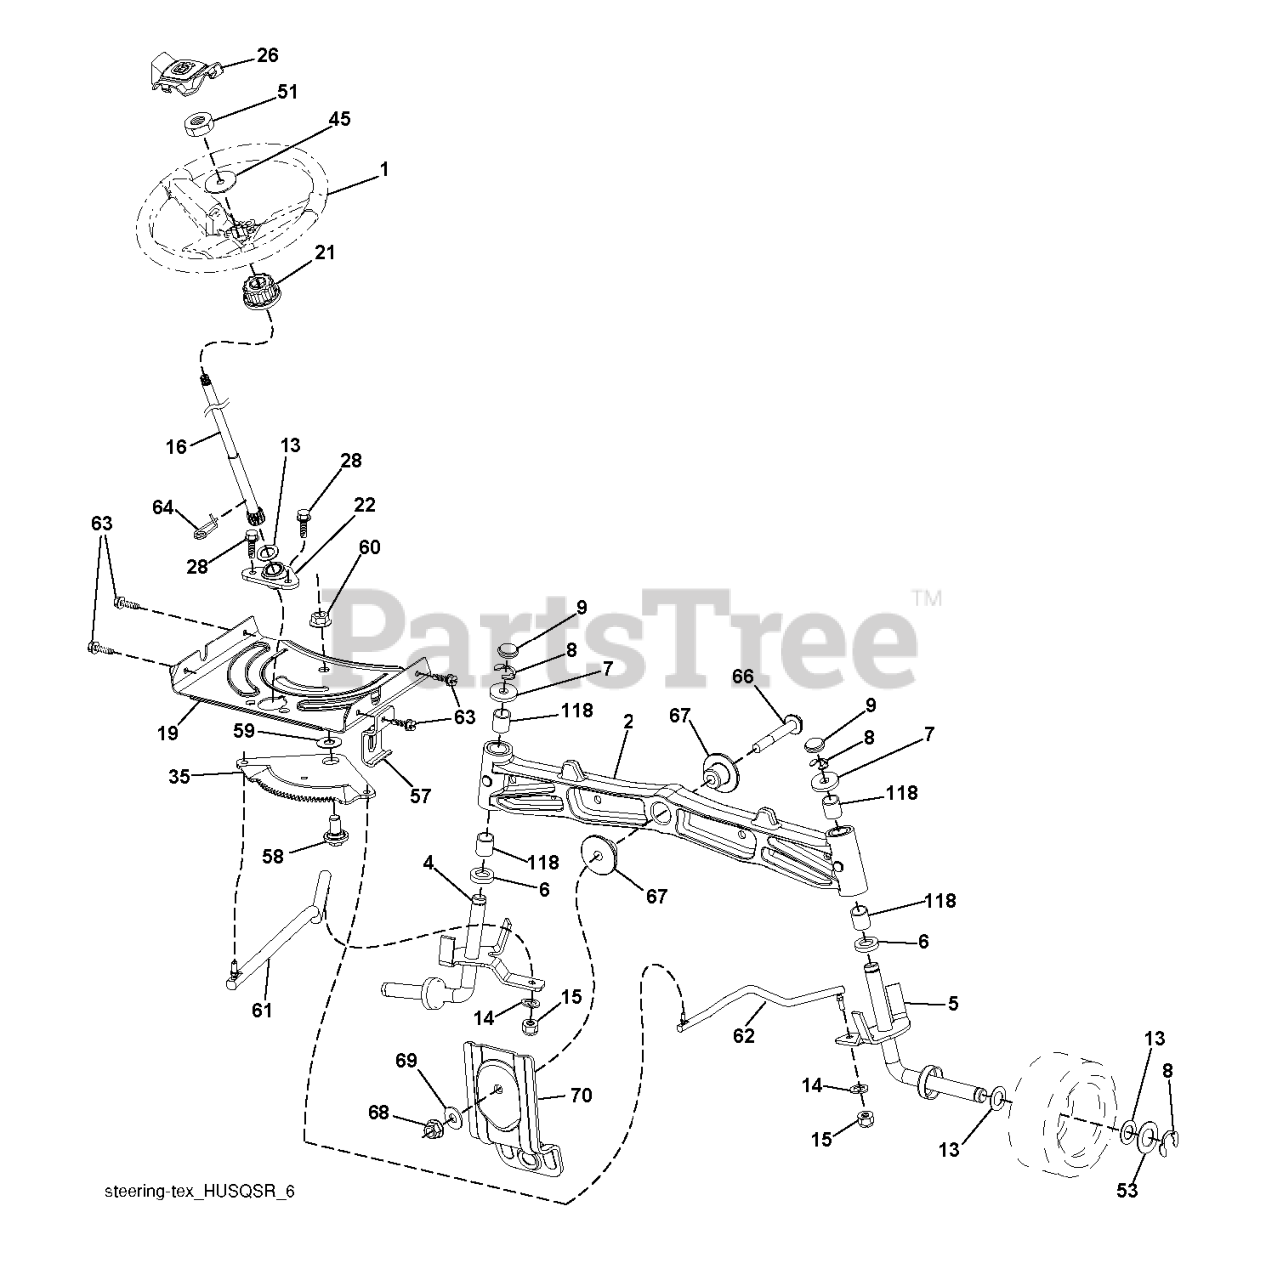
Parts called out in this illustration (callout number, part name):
1	RP WHEEL.STEER.HUSQ.PREM.OVMLD
2	AXLE.SVC.ASM CAST IRON.TEX
4	SPINDLE.WELDED.LH.16"TEX
5	SPINDLE.WELDED.RH.16"TEX
6	THRUST WASHER
9	CAP.SPINDLE.BLACK
14	WASHER, LOCK 3/8
15	NUT CROWNLOCK 3/8-24
16	SHAFT.STEER.STEALTH.DD
19	PLATE.STEER.DDL.NLT/NG
21	ADAPTER, WHEEL STNG..
22	BUSHING.ASM.STEERING.A
26	RP INSERT.CAP.WHL.STRG.HUSQ.
28	SCREW, 3/8-16X3/4
35	GEAR.SECTOR.PLATE.DDL.
45	WASHER 9/16"ID, 2 3/8"OD
51	NUT.HEX.1/2-20
53	WASHER.HARDENED
57	BRKT.UPSTOP.GT/LT.TEX
58	BOLT.SHOULDER.SECTOR.P
59	WASHER.THURST.SECTOR.S
60	NUT FLANGE LOCK 5/8-11
61	DRAGLINK.LH.BALLSTUD.D
62	DRAGLINK.RH.BALLSTUD.D
63	SCREW
64	RETAINER.CLIP.SPRING.S
66	BOLT HEX FGHD 7/16-14 X 3 SERR
67	BUSHING.PM.FRONT AXLE
68	NUT.LOCK.FLANGE.7/16
69	WASHER.1.5X.505X.118
70	BRKT.DECK.SUSPENSION.F
118	BUSHING, AXLE CAST
